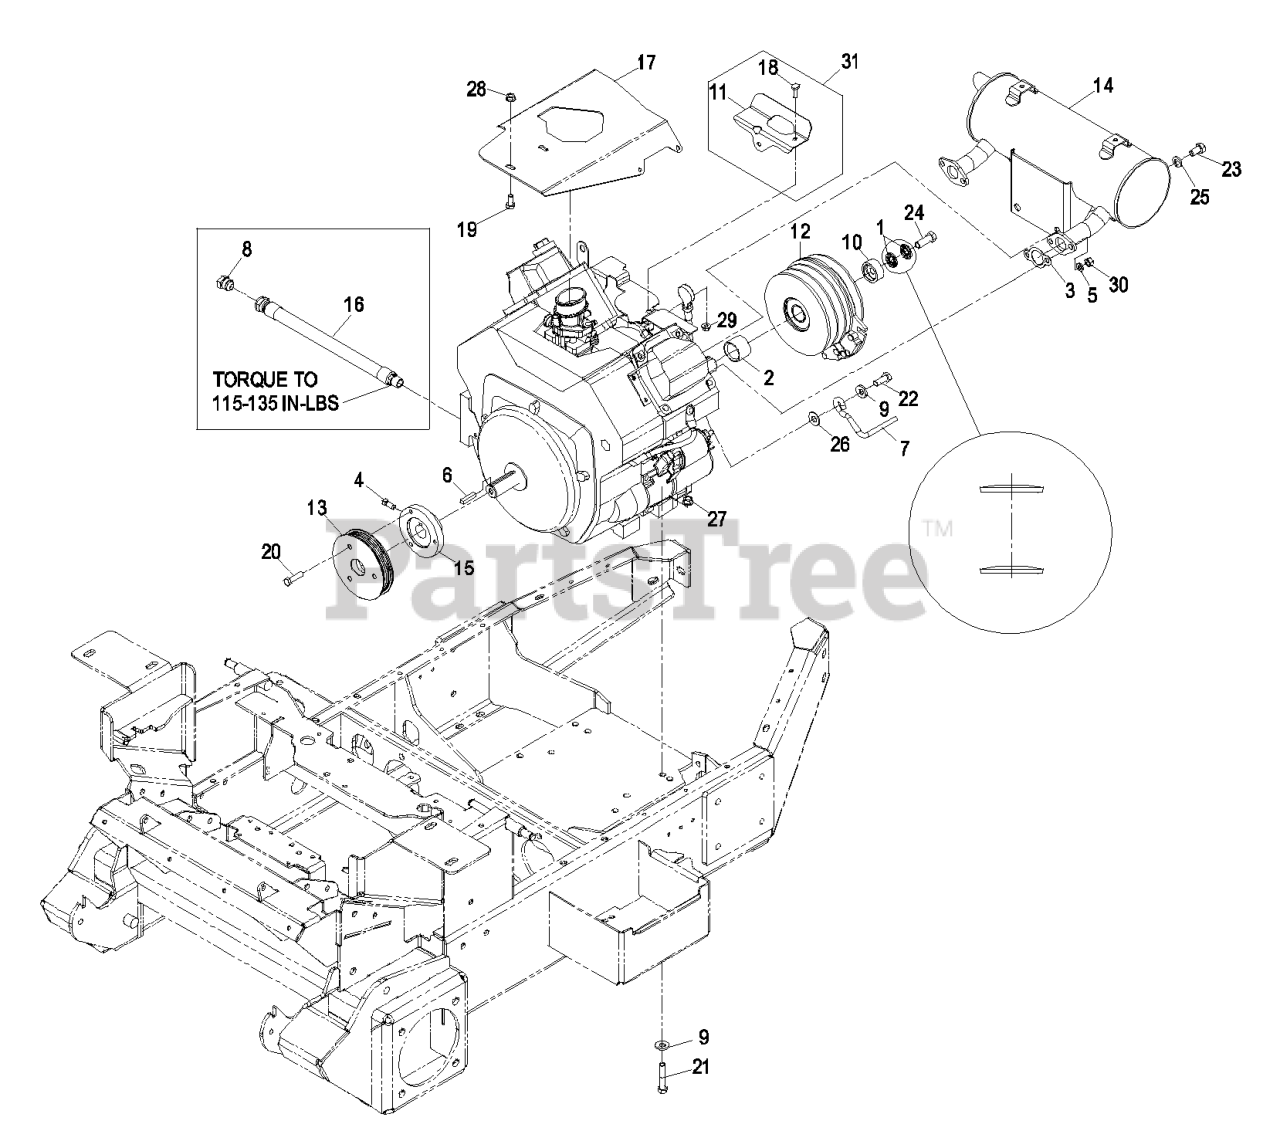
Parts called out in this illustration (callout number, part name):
1	WASHER-SPRING
2	SPACER-CLUTCH
4	SCREW-SET
5	WASHER-LOCK
6	KEY-SQUARE
7	ROD-BELT
8	PLUG
9	WASHER-BELLEVILLE
10	KEEPER-CLUTCH
11	CABLE HEAT SHIELD KIT
12	CLUTCH KIT
13	SHEAVE, 5K 4.63
14	KIT,MUFFLER KOHLER
15	HUB,ADAPTER (PLTD)
17	BRACKET, AIRCLNR FMZ-AC
18	SCREW-HH
19	SCREW-HH
20	SCREW-HH
21	SCREW-HH
22	SCREW-HH
23	SCREW-HH
24	SCREW-HH
25	SCREW-HH
26	WASHER-FLAT
27	NUT-HHF, WHIZ
30	NUT-HEX
31	CABLE HEAT SHIELD KIT
